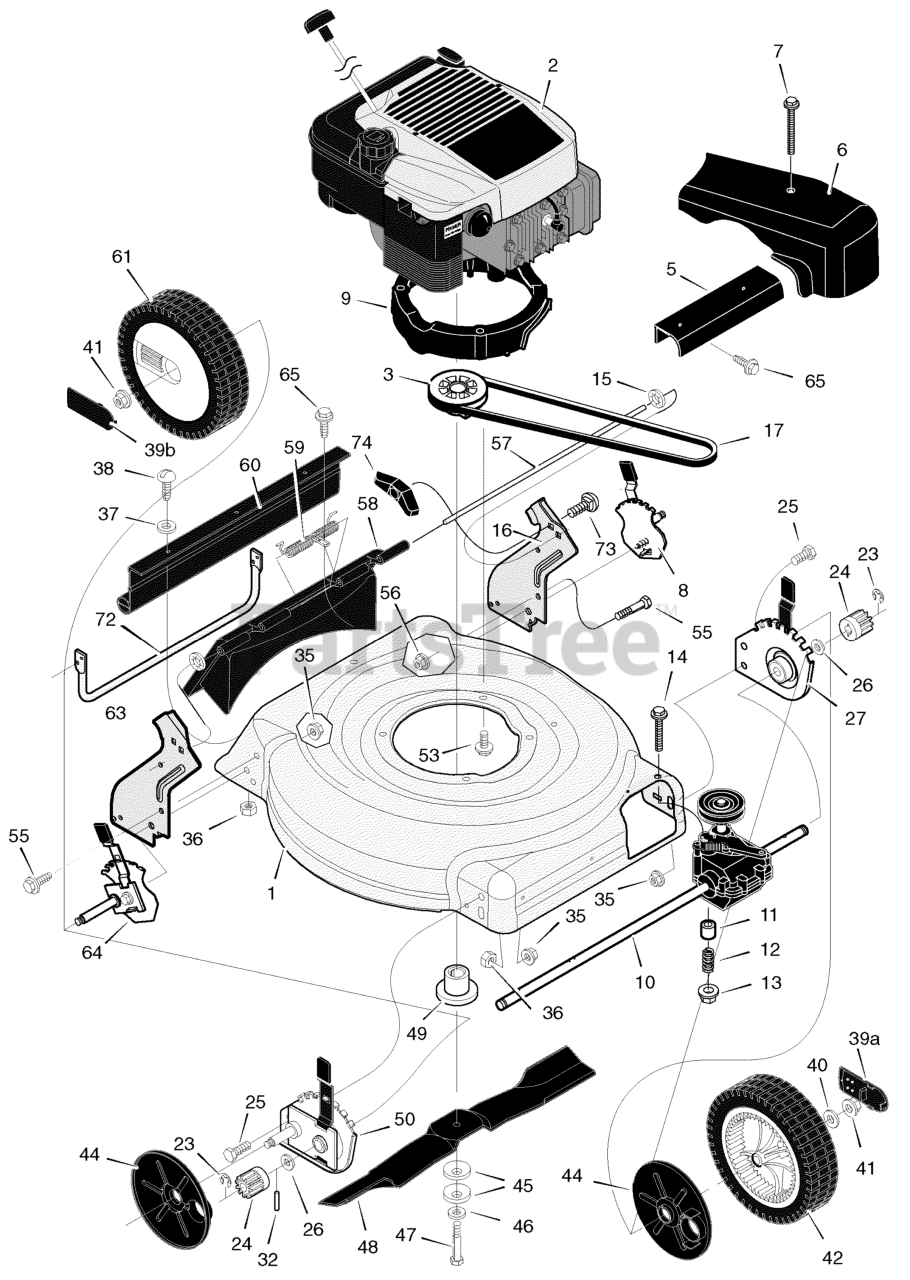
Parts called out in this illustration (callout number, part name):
1	Housing
2	Engine *
3	Pulley, Crankshaft
5	Cover, Axle (Gray)
6	Cover, Belt (Gray)
8	Adjuster, Left Height
9	Spacer, Engine
10	Transmission *
11	Spacer
12	Spring
13	Nut
14	Bolt
15	Retainer, Push
16	Bracket, Left Handle
23	E-Ring
24	Gear, Pinion
25	Bolt
26	Washer
27	Adjuster, Left Frt. Height
32	Pin, Drive
35	Nut, Flange
36	Nut, Hex
37	Washer
38	Screw
40	Washer
41	Nut, Flange
42	Wheel, Drive
44	Cover, Dust
45	Washer, Belleville
46	Washer
49	Adapter, Blade
50	Adjuster, Right Frt. Height
53	Bolt, Engine
55	Bolt
56	Nut, Flange
57	Rod, Pivot
58	Door, Rear (Gray)
59	Spring
60	Deflector, Rear
61	Wheel, Rear
63	Bracket, Right Handle
64	Adjuster, Right Height
72	Guard, Rear
73	Bolt, Carriage
